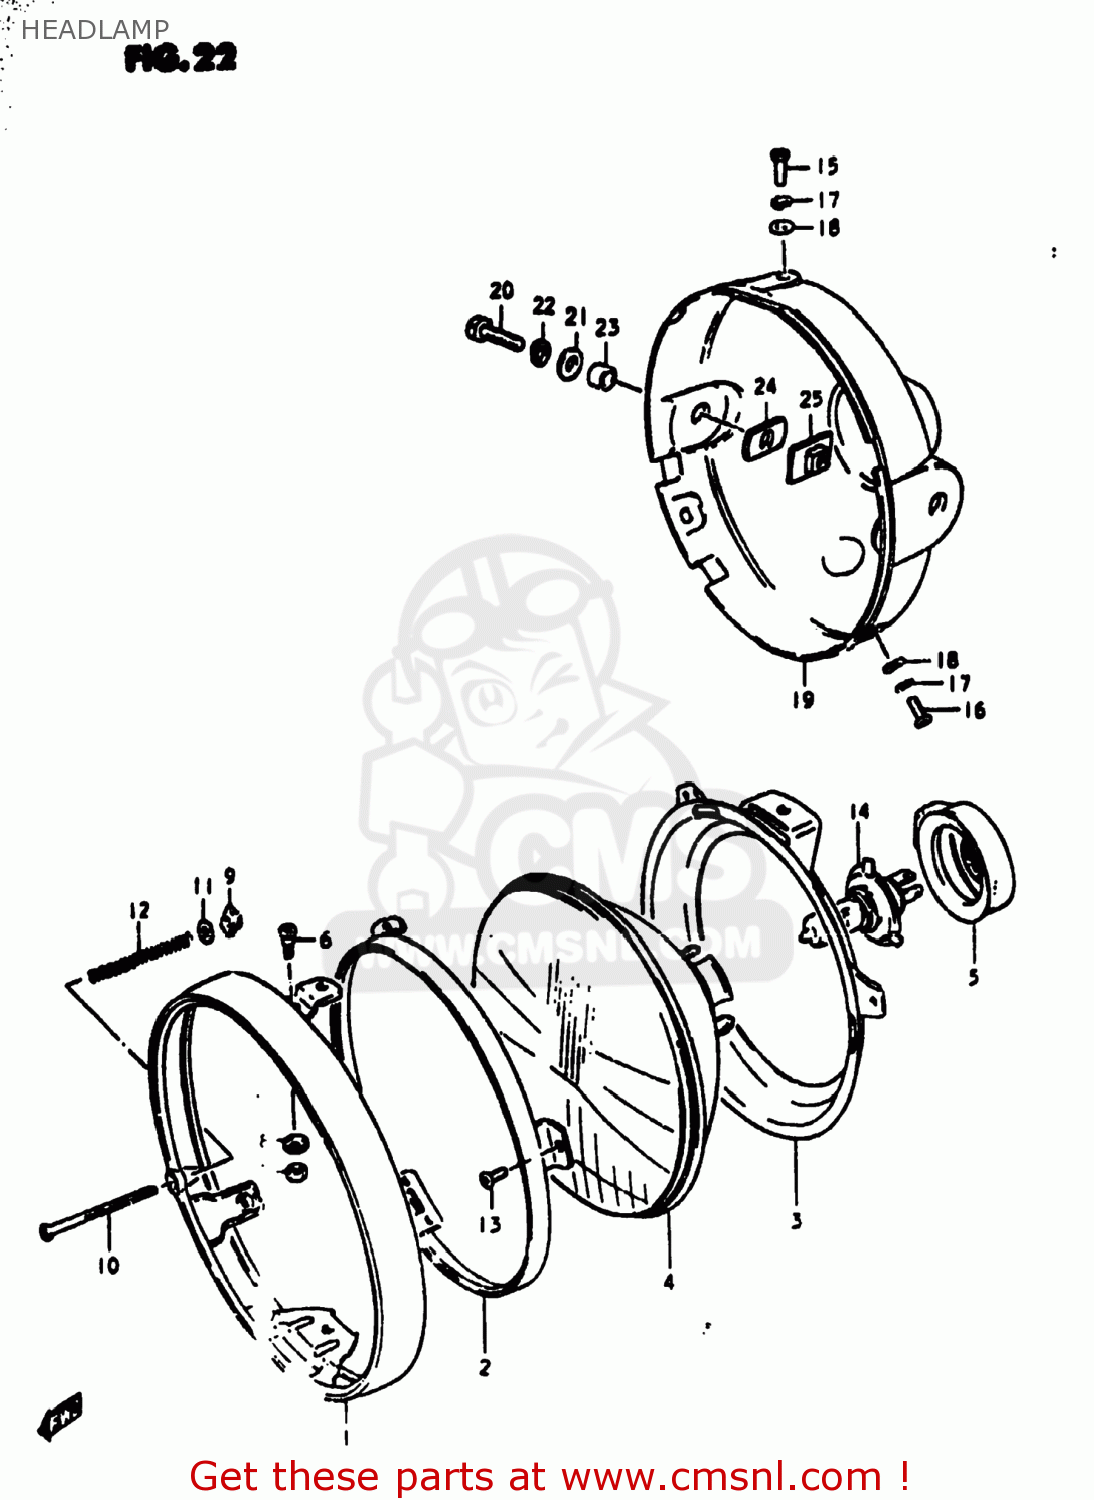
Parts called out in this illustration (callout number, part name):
1	RIM
2	RETAINER
3	RING,HEADLAMP UNIT
4	LAMP UNIT
5	COVER,HEADLAMP SOCKET
6	SCREW
7	NUT,ADJUSTING
8	SPACER
9	NUT
10	SCREW,HEADLAMP ADJUST
11	WASHER
12	SPRING,HEADLAMP ADJUST
13	SCREW
14	BULB(12V60/55W,H4)
15	BOLT
16	SCREW
17	LOCK WASHER
18	WASHER
19	HOUSING,HEADLAMP(BLACK)
20	BOLT
21	WASHER
22	LOCK WASHER
23	SPACER (8.8X12X7)
24	CUSHION
25	PLATE,HEADLAMP HOUSING
